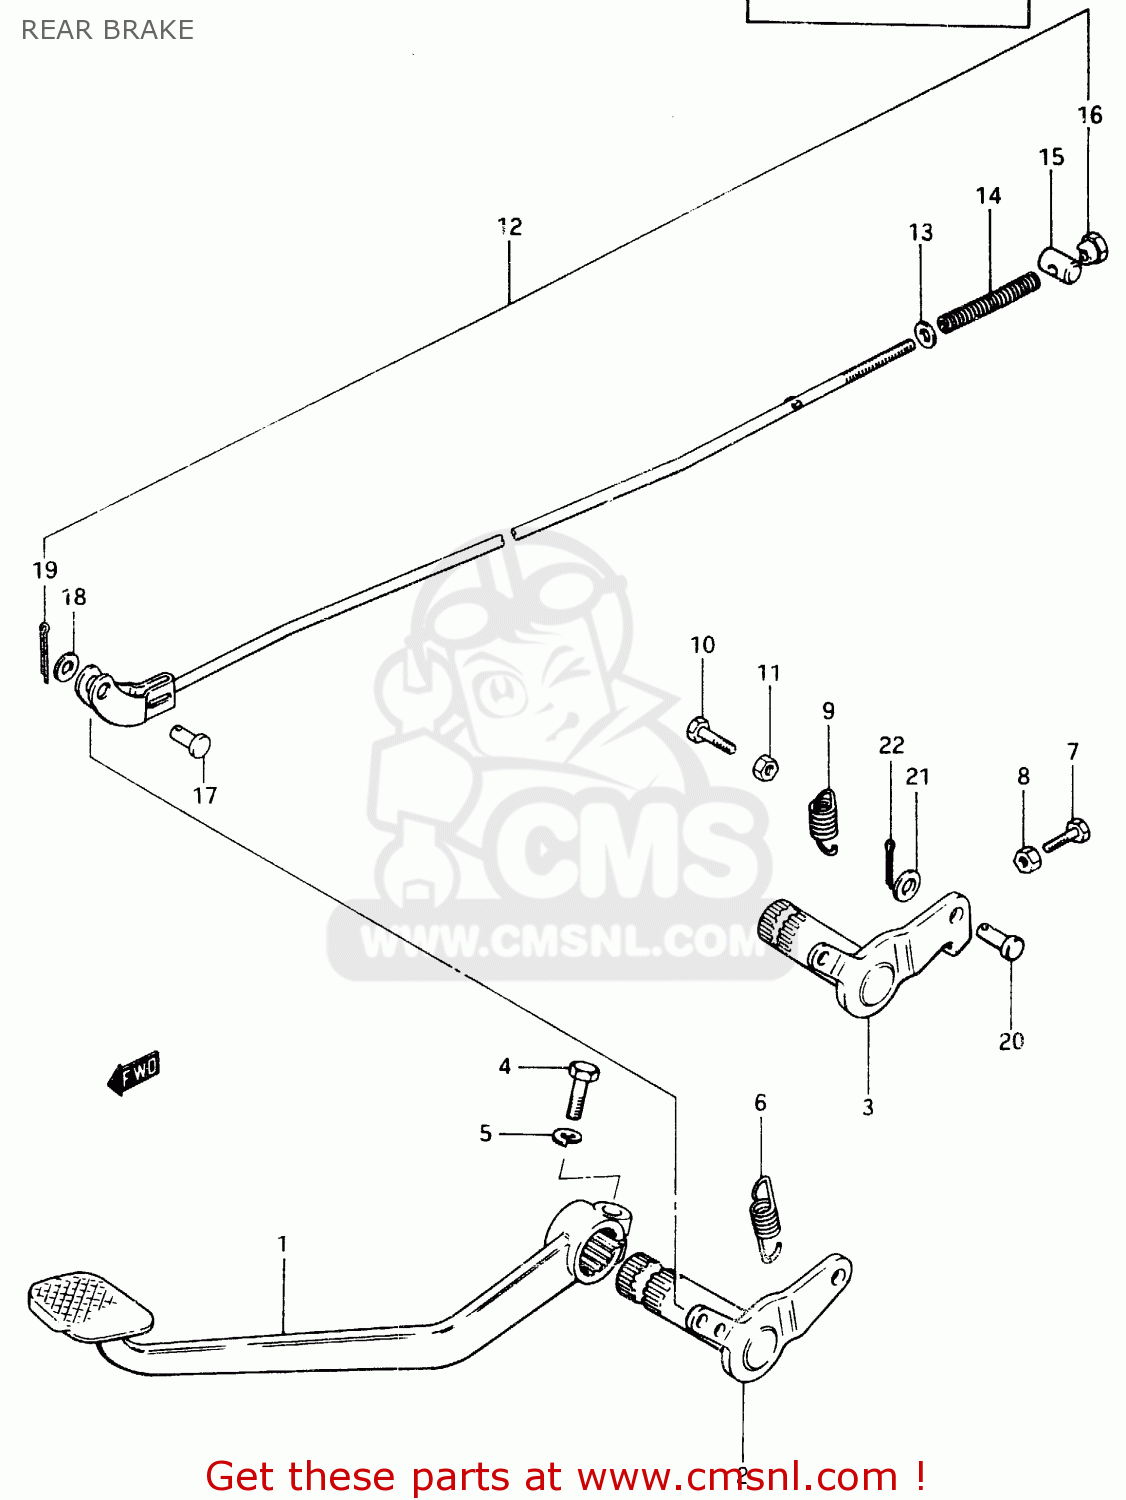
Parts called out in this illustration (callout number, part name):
1	PEDAL, BRAKE
2	ARM, BRAKE PEDAL ROD
3	ARM, BRAKE PEDAL ROD
4	BOLT
5	LOCK WASHER
6	SPRING
7	BOLT
8	NUT
9	SPRING
10	BOLT
11	NUT
12	ROD ASSY, REAR BRAKE
13	WASHER
14	SPRING
15	PIN
16	NUT (6MM)
17	PIN(L:13.5)
18	WASHER
19	PIN 20X20
20	PIN
21	WASHER
22	PIN
